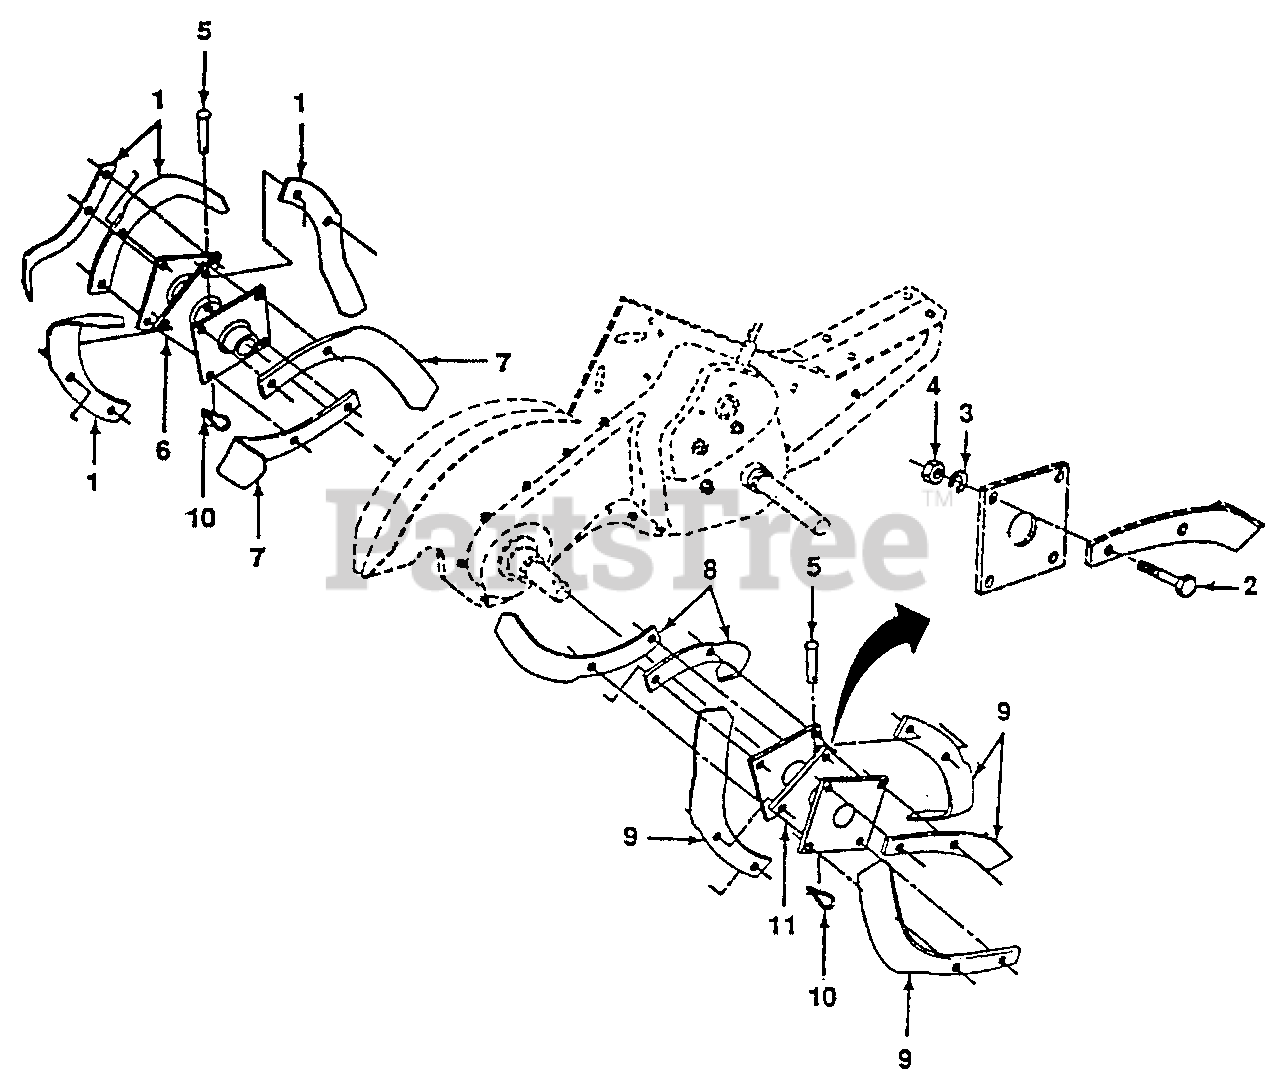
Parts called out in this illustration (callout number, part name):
1	Tine, L. H. Outer
2	Bolt, Hex 3/8-24 x 1
3	Washer, Lock 3/8
4	Nut, Hex 3/8-24
5	Clevis Pin
6	Assembly, Hub and Plate, L. H.
7	Tine, L. H. Inner
8	Tine, R. H. Inner
9	Tine, R. H. Outer
10	Clip, Hairpin
11	Assembly, Hub and Plate, R. H.
